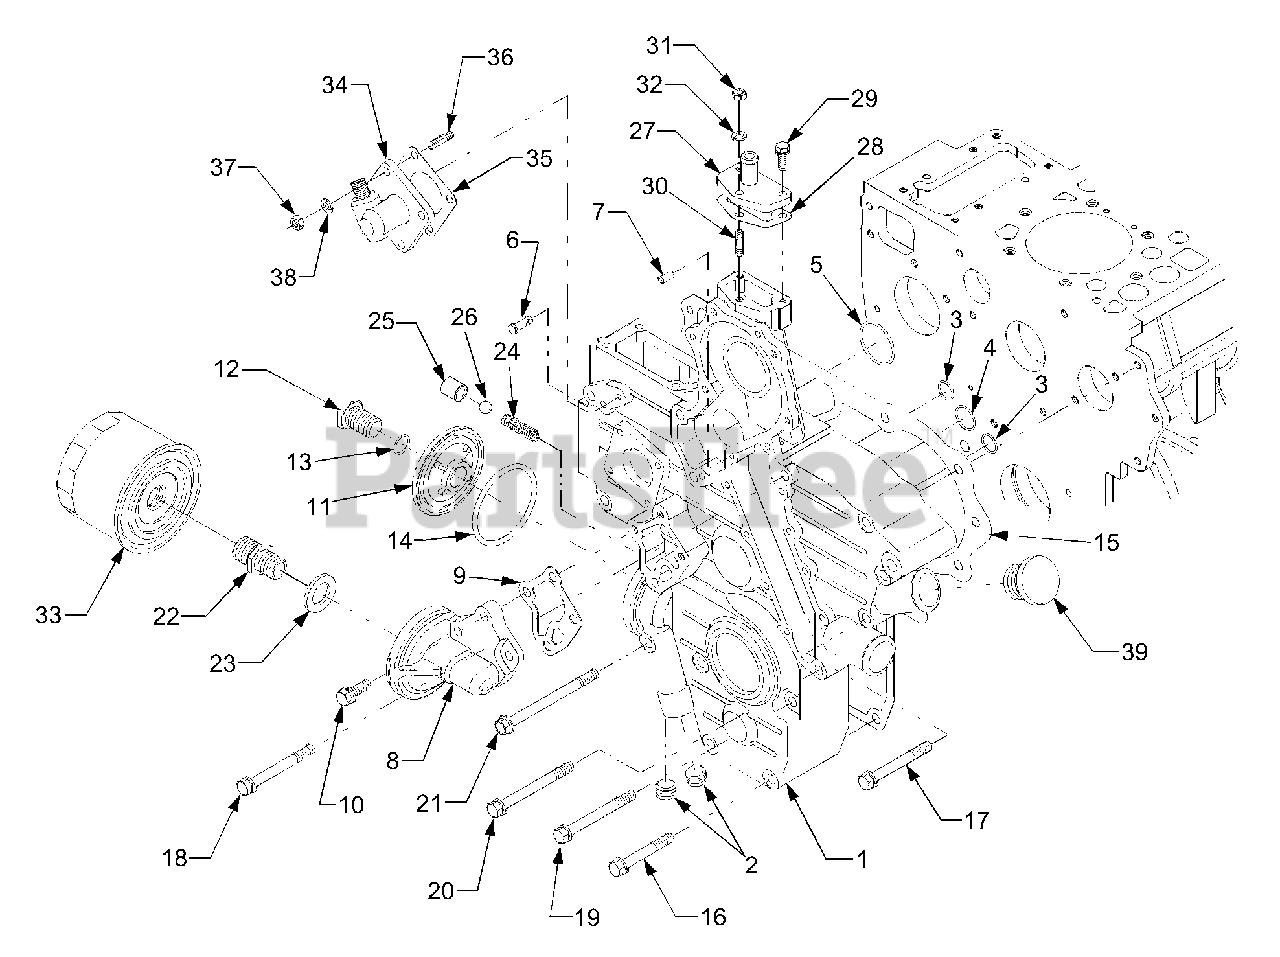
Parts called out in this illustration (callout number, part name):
1	Case, Gear
6	Pin, Start Spring
7	Pin, Straight
8	Support, Oil Filter
9	Gasket
15	Gasket, Gear Case
23	Washer, Plain
27	Flange, Water Return
32	Washer, Spring
33	Filter, Engine Oil
34	Hour Meter Ass'y
35	Gasket
38	Washer, Spring
39	Plug, Oil
